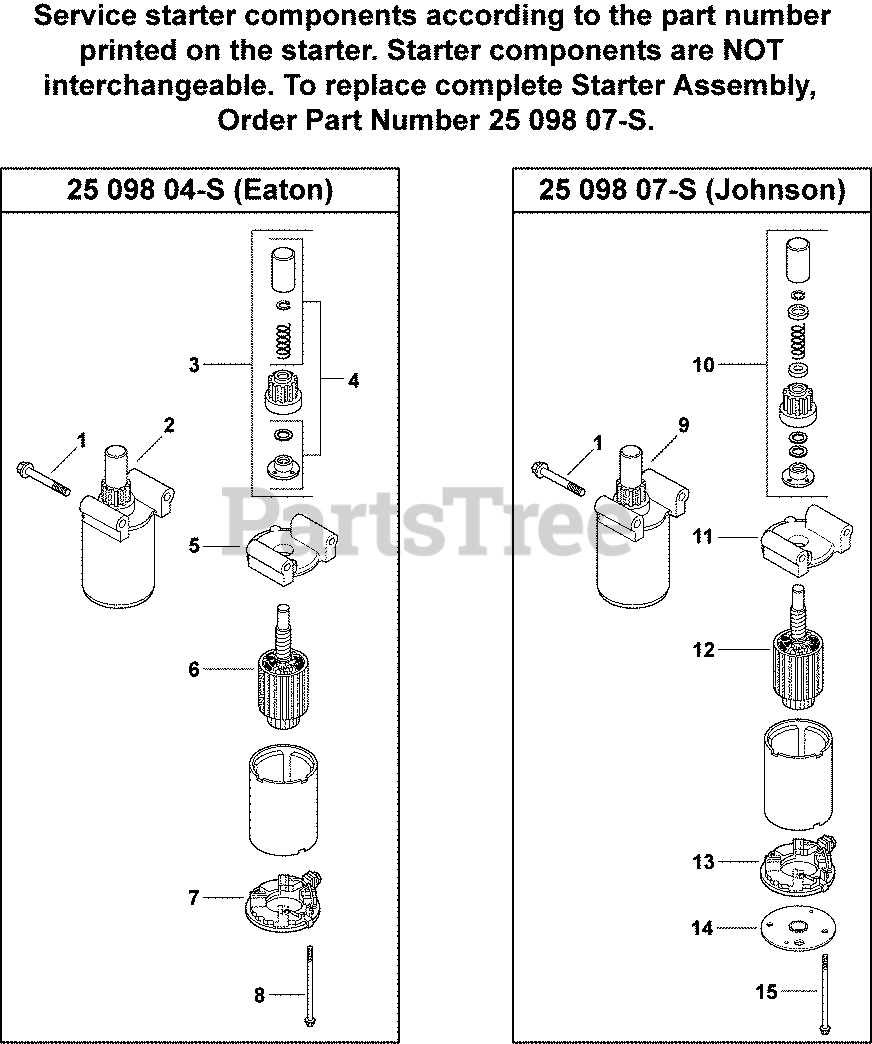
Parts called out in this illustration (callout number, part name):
1	SCREW, FLG M8X1.25X70
3	KIT,DR W/GEAR (FASCO/V.WEISE/W&G)(#DSC)
4	KIT, DR PTS(FASCO/V.WEISE/W&G) - DISC.
5	CAP, DRIVE END - DISCONTINUED
6	ARMATURE - (#DSC)
7	BRUSH ASSY (FASCO/V.WEISE/W&G)-DISC.
8	SCREW - DISCONTINUED
9	ELECTRIC STARTER-BENDIX DRIVE
10	KIT, DRIVE
11	CAP, DRIVE END - (#DSC)
12	ARMATURE - DISCONTINUED
13	BRUSH KIT - (#DSC)
14	CAP - DISCONTINUED
15	BOLT, THRU #10-24X4 13/32" - DISCONTINUED
